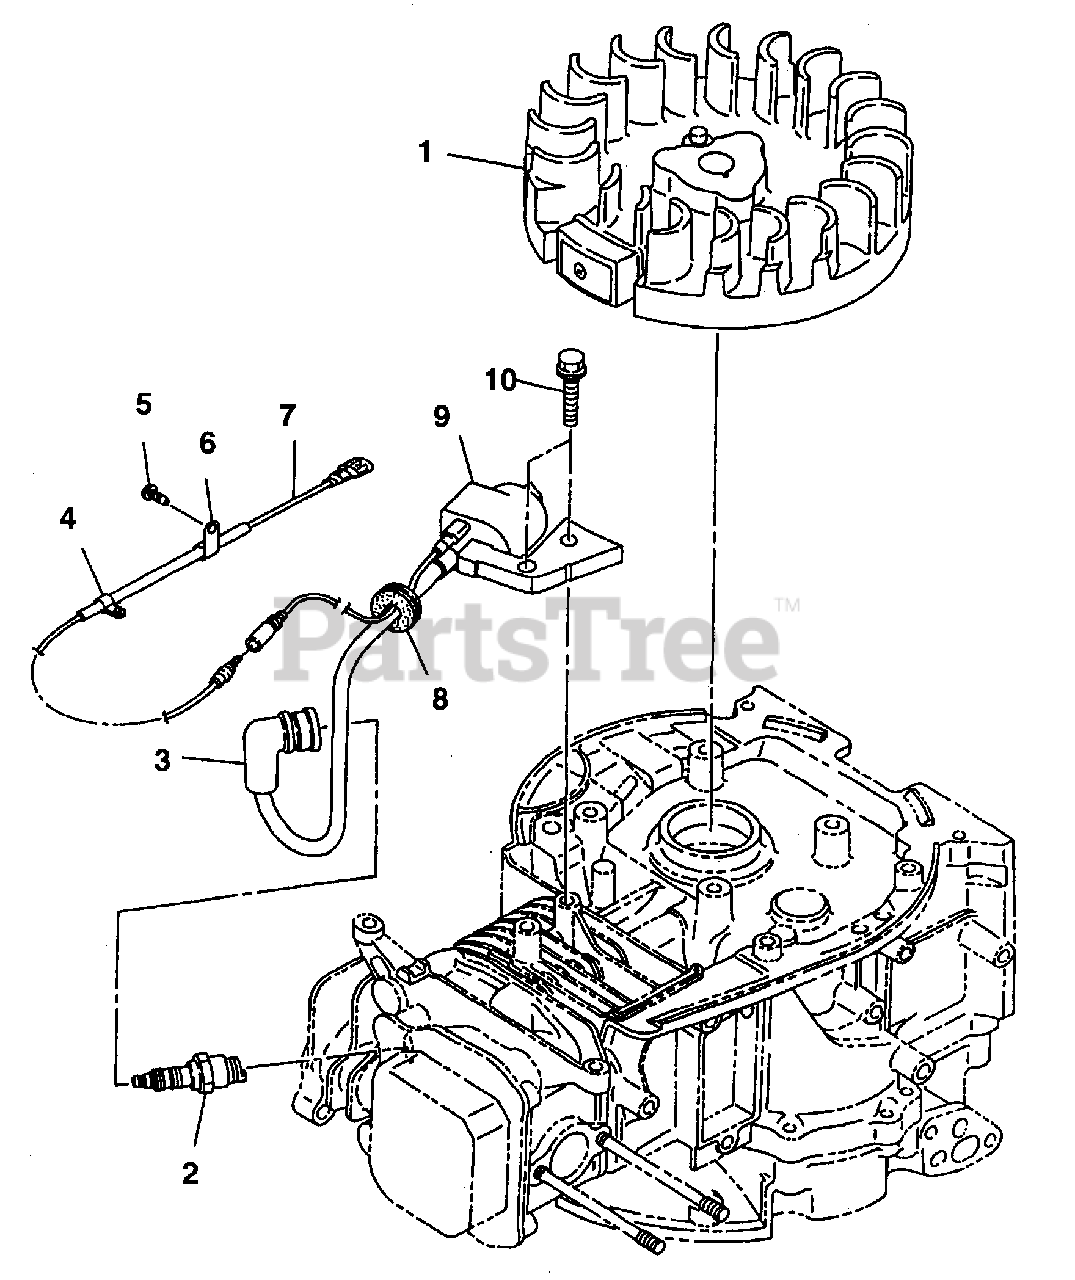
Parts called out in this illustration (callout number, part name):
1	FLYWHEEL
2	SPARK PLUG
3	SPARK PLUG CAP
5	SCREW, Tapping
9	COIL, Ignition
10	BOLT, Flange
